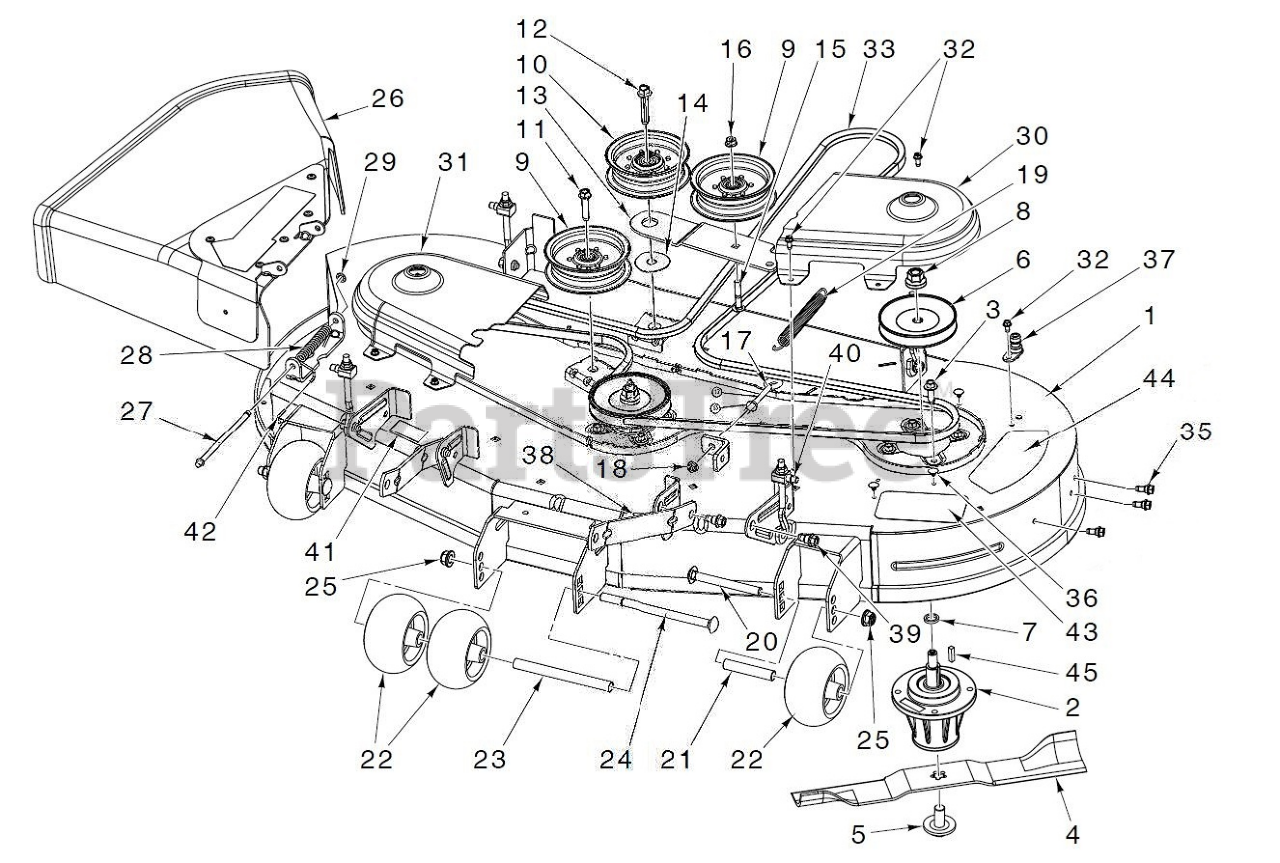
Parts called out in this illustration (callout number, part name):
1	DECK.SVC.54.CLRCT.MZ.MS668
3	BOLT.HEX.WASHR.HED.313-18X1.19
4	BLADE.54CC.HI-LIFT.PZ.197".431
5	BLADE BOLT/WASHER
7	WASHER.SPACER.MANDREL
8	NUT FLANGE 3/4-16
9	PULLEY.IDLER.2006
10	PULLEY.IDLER.MWR.STATI.LH
11	BOLT;HEX_3/8-16 X 1.78.CLRZINC
12	SCREW.7/16-14 X 2.125.WASHER
13	ARM IDLER ARM, CLEARCUT 54 BLA
16	NUT LOCK FLG 3/8-16 UNC
17	GSPW Bolts
18	GSPW Hardware
19	SPRING.MOWER.DRIVE.ELECTRIC
22	ROLLER, GAUGE .635 BORN
25	NUT 1/2-13 HEX FLANGE NYLOK CL
26	DEFLECTOR ASSY 54 CLEARCUT RES
27	ROD.HINGE
28	SPRING.42.FCS.DEFLECTOR
29	NUT PUSH M
30	COVER.PNT.54CC.MNDRL.LH.ZTR.GY
31	COVER 54 CLEARCUT RH MANDREL G
32	SCREW.1/4-20X5/8
33	Belts
35	SHOULDER BOLT 5/16-18TT
36	PLUG CHRISTMAS TREE
37	PORT.WASHOUT
38	ARM.RFIXED.MOWER.SUSPNSIONX431
39	BOLT.SHOULDER
40	NUT.HEX.FLANGE.INS.BLK.3/8-16
40	LINK.ASM.ADJUSTABLE
41	DECAL BELT ROUTING DECAL DECAL
42	CAP-SLEEVE LT
44	DECAL DECK DECAL DECAL.54DECK.
45	KEY 1/4 SQ X 1.0
